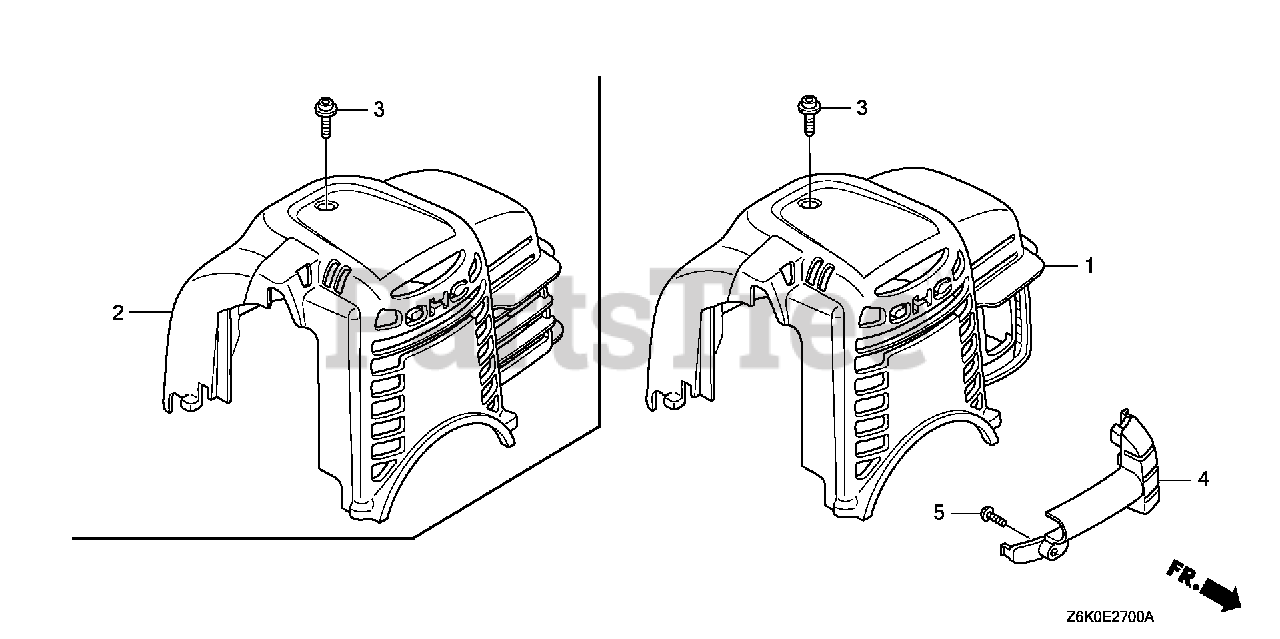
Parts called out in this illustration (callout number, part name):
2	COVER, TOP *R280* (POWER RED)
2	COVER, TOP *NH1* (BLACK)
3	BOLT, TOP COVER
